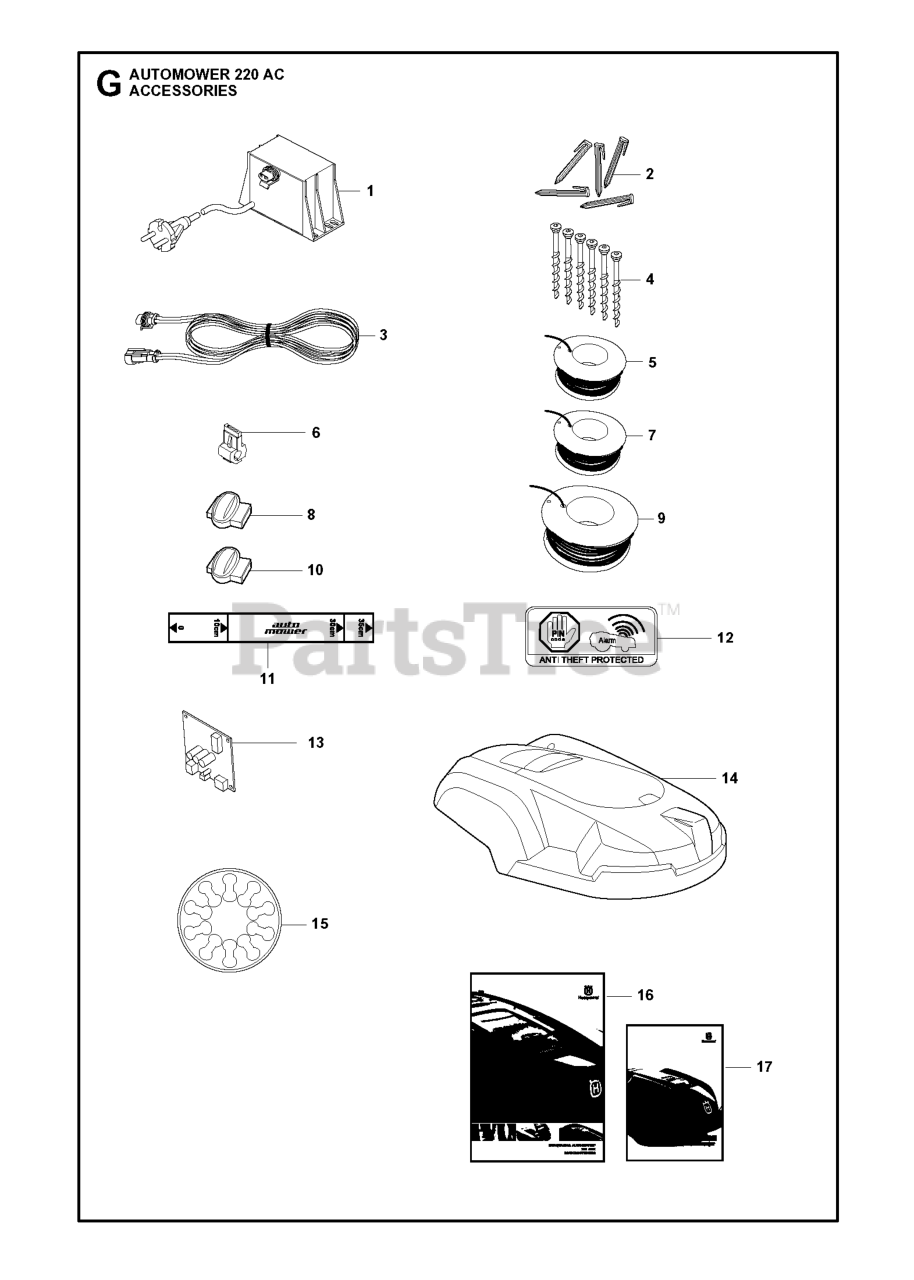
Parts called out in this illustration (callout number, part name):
1	TRANSFORMER
1	TRANSFORMER/US
2	STAPLES (100 CT BAG)
2	STAPLE 100 PCS, BLISTER
3	LOW VOLT WIRING
4	SCREW 3 PCS, BLISTER PACK
4	SCREW KIT CS
5	WIRE 150M, BLISTER
5	LOOP WIRE 150M
6	CONNECTOR 5 PCS, BLISTER
6	BRAKER
7	LOOP WIRE 250M
8	SPLICE KIT
8	COUPLER SPLICER, 5 PCS,
9	WIRE 500M
10	SPLICE CONNECTOR 50 PCS/PK
11	RULER / CENTIMETERS
13	PRINTED CIRCUIT ASSY
14	BODY AIR, CREAM WHITE
14	BODY WATER, DARK BLUE
14	BODY EARTH, BROWN
14	BODY FIRE, ORANGE
